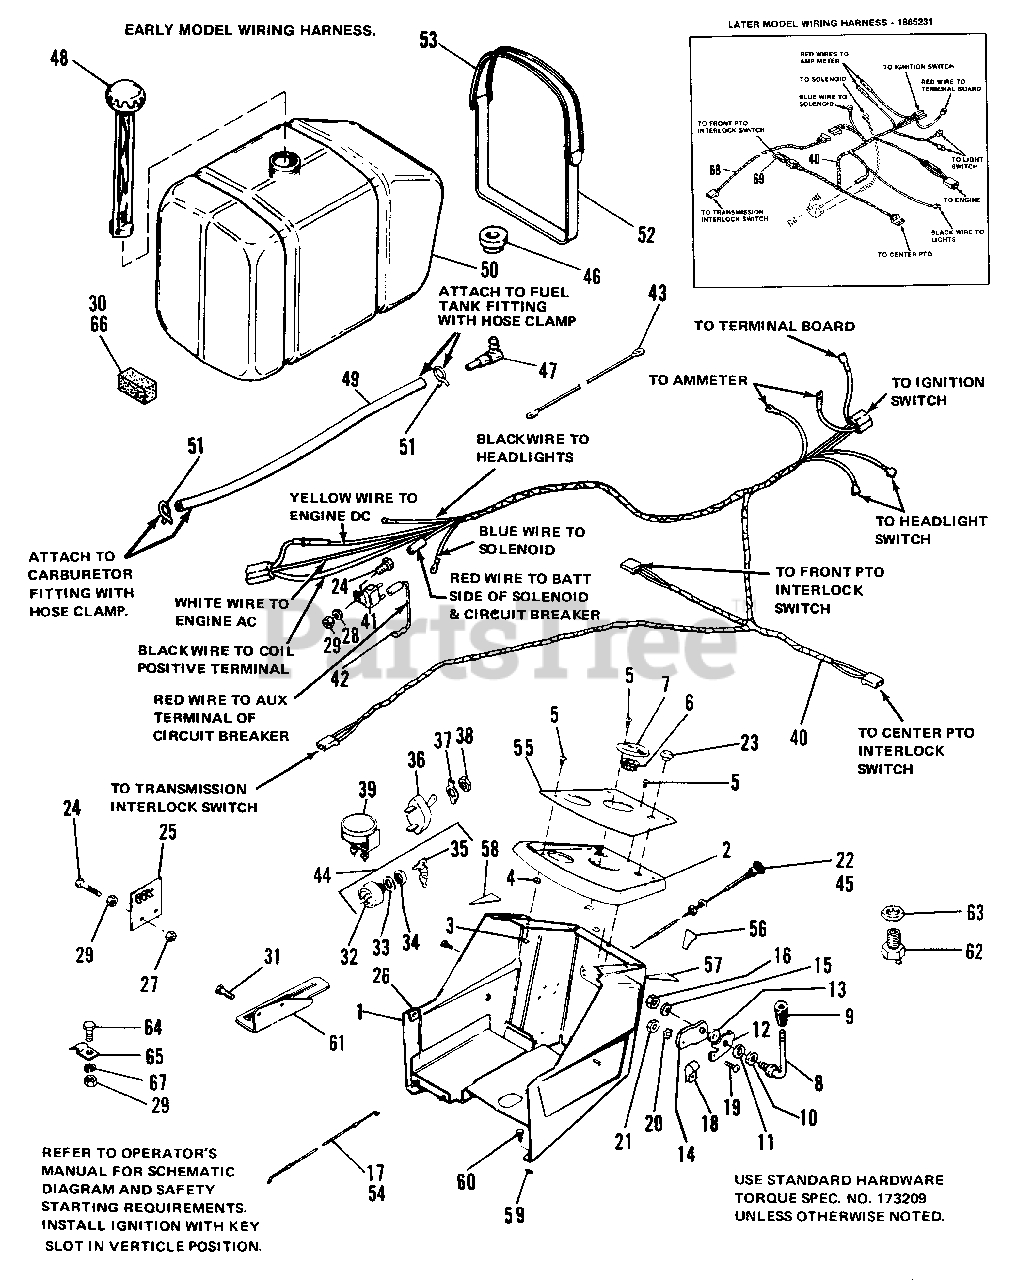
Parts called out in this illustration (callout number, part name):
1	DASH ASSEMBLY
2	PANEL, Instrurnent
3	NUT, Retainer, Tinn.
4	WASHER, Plain, 3/16
5	SCREW, Mach. Rd. Hd., 1/4-20 x 1/2
7	PLATE STEERING, Adj.
8	HANDLE, Clutch Control
9	KNOB, Tapered
12	STOP,Throttle Kit (inc. ref. 10, 11)
14	ARM, Throttle
15	LOCKWASHER, Dished Shakeproof, 3/8
16	LOCKNUT, Hex, 3/8-16
17	CONTROL, Throttle (7012 Only)
18	CLIP, Bowden Wire
19	SCREW, Rd. Hd., No. 10-32 x 1/2
20	LOCKWASHER, External, No. 10
21	NUT, Mach. Hex, No. 10-32
22	CONTROL, Choke (7012 Only)
23	PLUG, Button
24	CAPSCREW, Hex Hd, 1/4-20 x 5/8
25	BOARD, Terminal
26	CLIP, Wire
27	NUT, Lock, Hex, 1/4-20
28	LOCKWASHER, Shakerproof, 1/4
29	NUT, Hex, 1/4-20
30	GASKET, Felt (7018 Only)
31	SCREW, Special
32	SWITCH, Ignition
33	LOCKWASHER, Internal, 5/8
34	NUT, Hex Special
36	SWITCH, Toggle
37	PLATE
38	NUT
40	HARNESS ASSEMBLY (1690352 Only)
40	HARNESS ASSEMBLY (1690366 Only)
40	HARNESS ASSEMBLY (1690431 Only)
40	HARNESS ASSEMBLY (1690433 Only)
41	CIRCUIT BREAKER
42	WIRE ASSEMBLY
43	WIRE ASSEMBLY
44	SWITCH, Key Assy.
45	CONTROL, Choke (7018 Only)
47	FITTING, Fuel Tank
48	CAP, Fuel Tank
50	TANK ASSY, Fuel, Inc. Ref. No's 46, 47, 49 & 51
51	CLAMP, Hose
52	STRAP, Tank
53	STRAP, Fuel Tank
54	CONTROL, Throttle (7018 Only)
55	DECAL, Instrument Panel
56	DECAL, Ignition
57	DECAL, Throttle Control
58	DECAL, Hydrostatic Control
59	NUT, Speed, Tinn.
60	SCREW, Hex Hd. Thd. Forming, No. 14 x 3/4
61	QUADRANT
62	SWITCH, Interlock
63	NUT, Pal
64	CAPSCREW, Hex, Hd., 1/4-20 x 3/4
65	CLIP, Cable
66	PAD, Fuel Tank (7012 Only)
67	LOCKWASHER, 1/4
68	WIRE ASSY. (Used only w/Wiring Harness No. 1665231)
69	WIRE ASSY. (Used only w/Wiring Harness No. 1665231)
